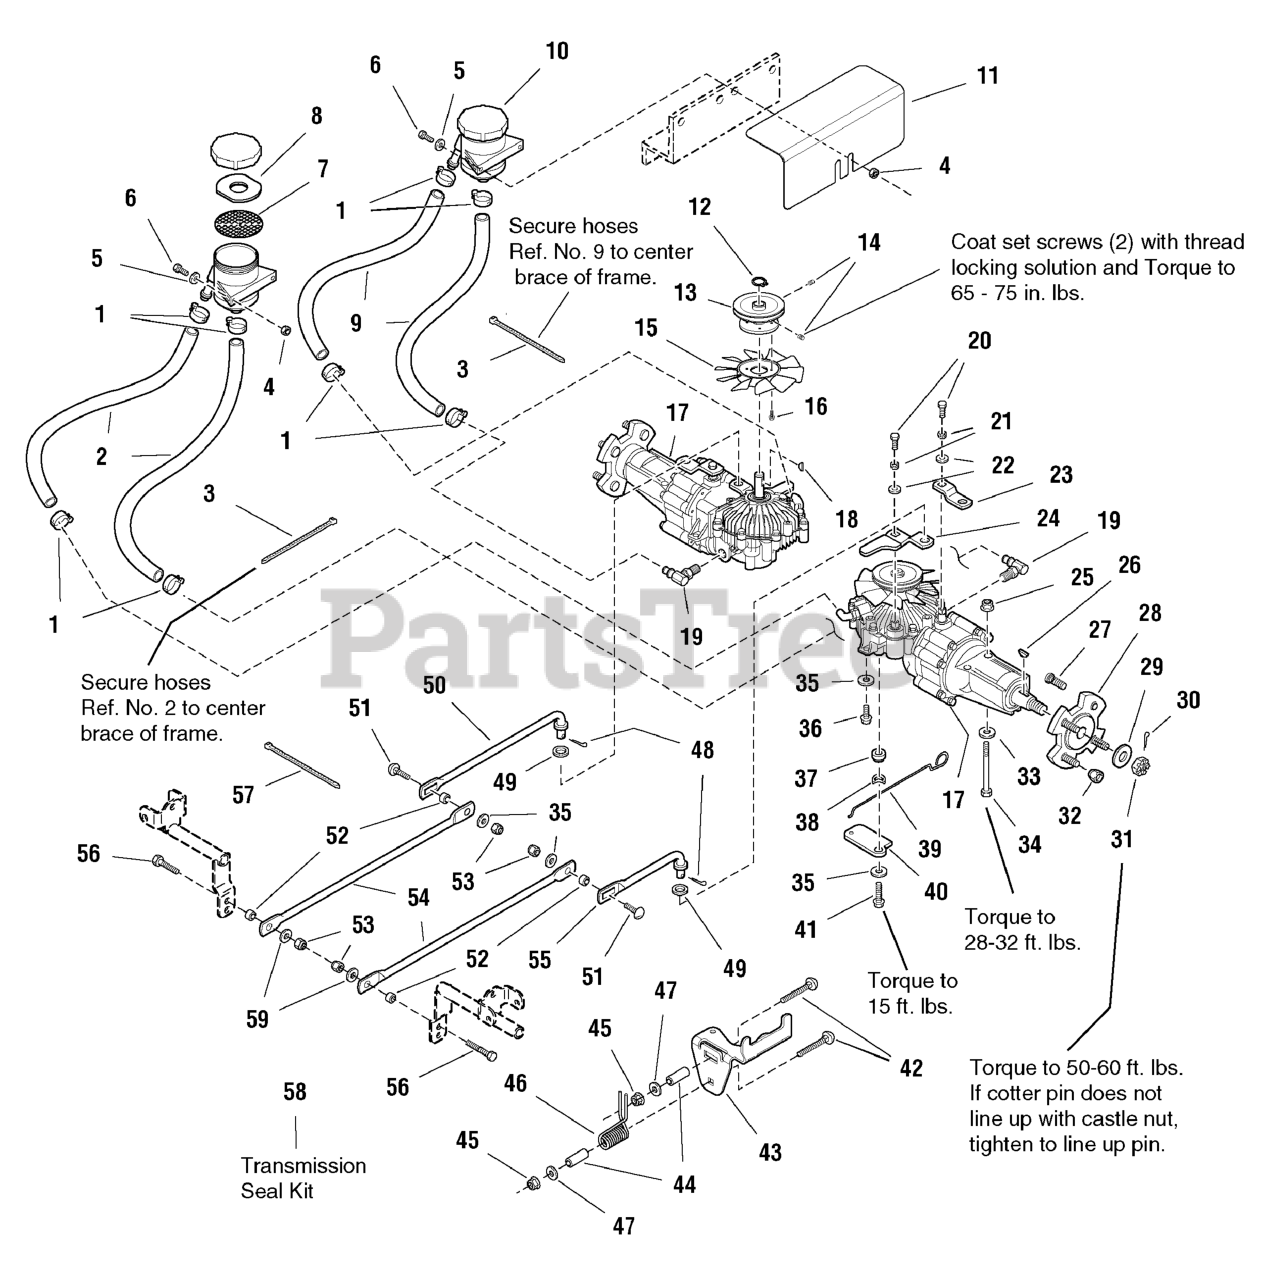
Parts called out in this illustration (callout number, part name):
1	CLAMP, Hose, Wire Type E
2	HOSE, Hydraulic
3	TIE, Self Locking
4	NUT, Hex, Whiz Lock, Flange, 1/4-20
5	WASHER, 1/4
6	CAPSCREW, Hex Head, 1/4-20 x 5/8, G5
7	FILTER, Reservoir
8	WASHER, Special
9	HOSE, Hydraulic
10	RESERVOIR, Hydro Expansion
11	COVER, Reservoir
12	RING, Retaining
14	SET SCREW, Torx Head Cup Point, 1/4-28 x 1/4, G8
15	FAN, 10 Blades, 6" Plastic
16	CAPSCREW, Hex Washer Head Taptite, 1/4-20 x 5/8
17	TRANSMISSION ASSEMBLY
18	KEY, Hi-Pro
19	FITTING, Hose Elbow, 3/8-18
20	CAPSCREW, Hex Head, 1/4-28 x 5/8, G5
21	LOCKWASHER, Spring, 1/4
22	WASHER, Flat, 1/4
23	ARM, Transmission Brake
24	ARM, Control
25	NUT, Hex Flange Two-Way Lock, 3/8-16
26	KEY, #15, 1/4 x 1
27	BOLT, Wheel Knurled, 7/16-20 x 1
28	PLATE & HUB ASSEMBLY, Rear Wheel
29	WASHER, 3/4
30	PIN, Cotter
31	NUT, Hex Slotted, 3/4
32	NUT, Hex, 7/16-20, for Wheel Bolt
33	WASHER, 5/16
34	CAPSCREW, Hex Head, 3/8-16 x 3-1/4, G5
35	WASHER, 5/16
36	CAPSCREW, Hex Head Taptite, 5/16-18 x 3/4
38	WASHER, Shakeproof, 1/2
39	ROD, Actuator
40	ACTUATOR, Tow Valve
41	CAPSCREW, Hex Washer Head Taptite, 5-16-18 x 1
42	CARRIAGE BOLT, 5/16-18 x 2-1/4
43	SUPPORT, Neutral Return
45	NUT, Flange ESNA, 5/16-18
46	SPRING, Torsion
47	WASHER, Flat, 5/16
48	PIN, Cotter
49	WASHER, 1/2
50	LINK, Control Rear, R.H.
51	BOLT, Carriage, Short Neck, 5/16-18 x 1
53	NUT, Hex ESNA Light Lock, 5/16-18
54	ROD, Control
55	LINK, Control Rear, L.H.
56	CAPSCREW, Hex Head, 5/16-18 x 1
57	TIE, Self Locking
58	* SEAL KIT, Transmission
59	WASHER, 5/16
